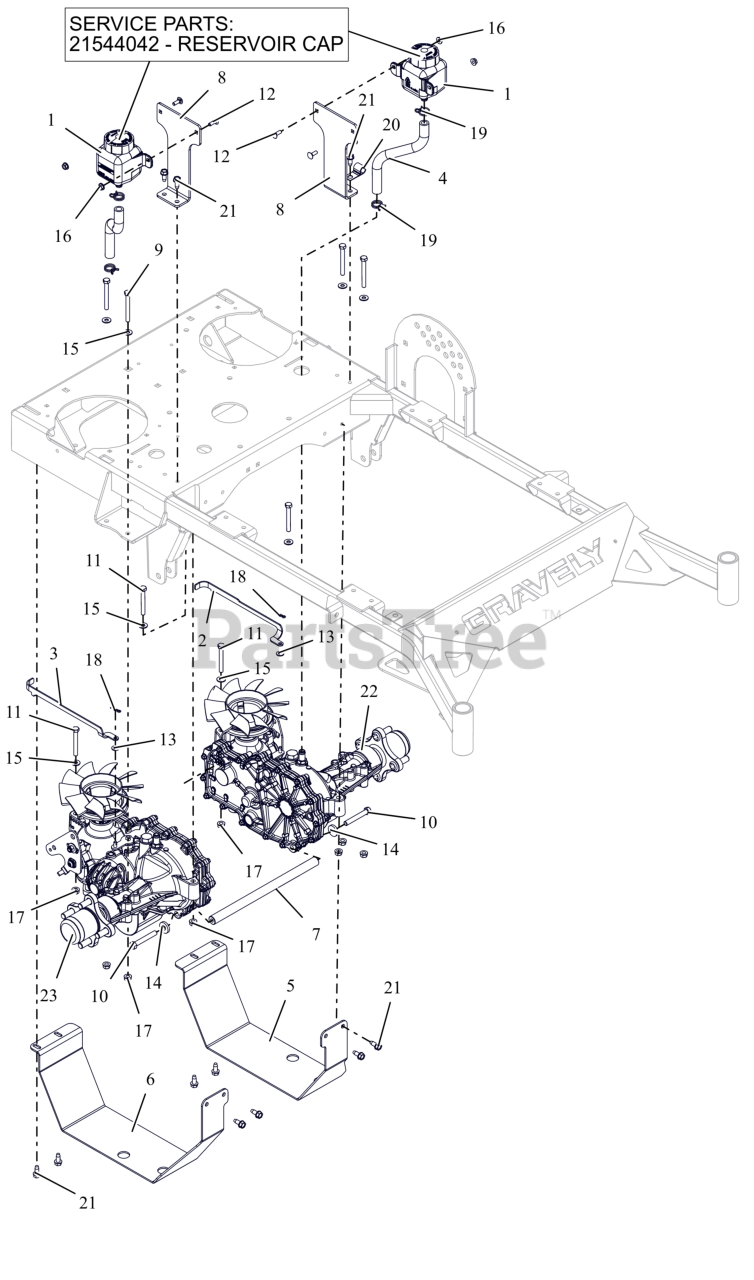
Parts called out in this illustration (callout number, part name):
1	TANK, EXPANSION
1	CAP, HYDRO RESERVOIR REPLAC.
2	BRKT, LH DUMP VALVE (BLACK)
3	BRKT, RH DUMP VALVE (BLACK)
4	HOSE, PRO WALK OVERFLOW
5	PLATE, LH SKID (BLACK)
6	PLATE, RH SKID (BLACK)
7	SHAFT, CROSS BRACE
8	BRKT, EXPANSION TANK MTG (RED)
9	BLT, HEX .31-18X2.75 G5 ZCC
10	BLT, HEX .38-16X2.50 G5 ZCC
11	BLT, HEX 0.3125-18X2.5 GR5 ZCC
12	BLT, RHSN .25-20X.750 G5 ZCC
13	WSHR,FLT .281X.625X.065 ZCC
14	WSHR, FLT .406X1.00X.188 ZCC
15	WSHR, FLT .312X.734X.065 ZCC
16	NUT-LK-CTR-FLG .25-20 ZC120
17	NUT,LK-CTR-FLG .31-18 GF ZCC
18	PIN, HAIR #225 .072X1.09
19	3/4 WIRE HOSE CLMP ZC
21	SCR,TAP .312-18X.75 HWH TR ZCC
22	TRANSAXLE, ZT2800 - LH
23	TRANSAXLE, ZT2800 - RH
